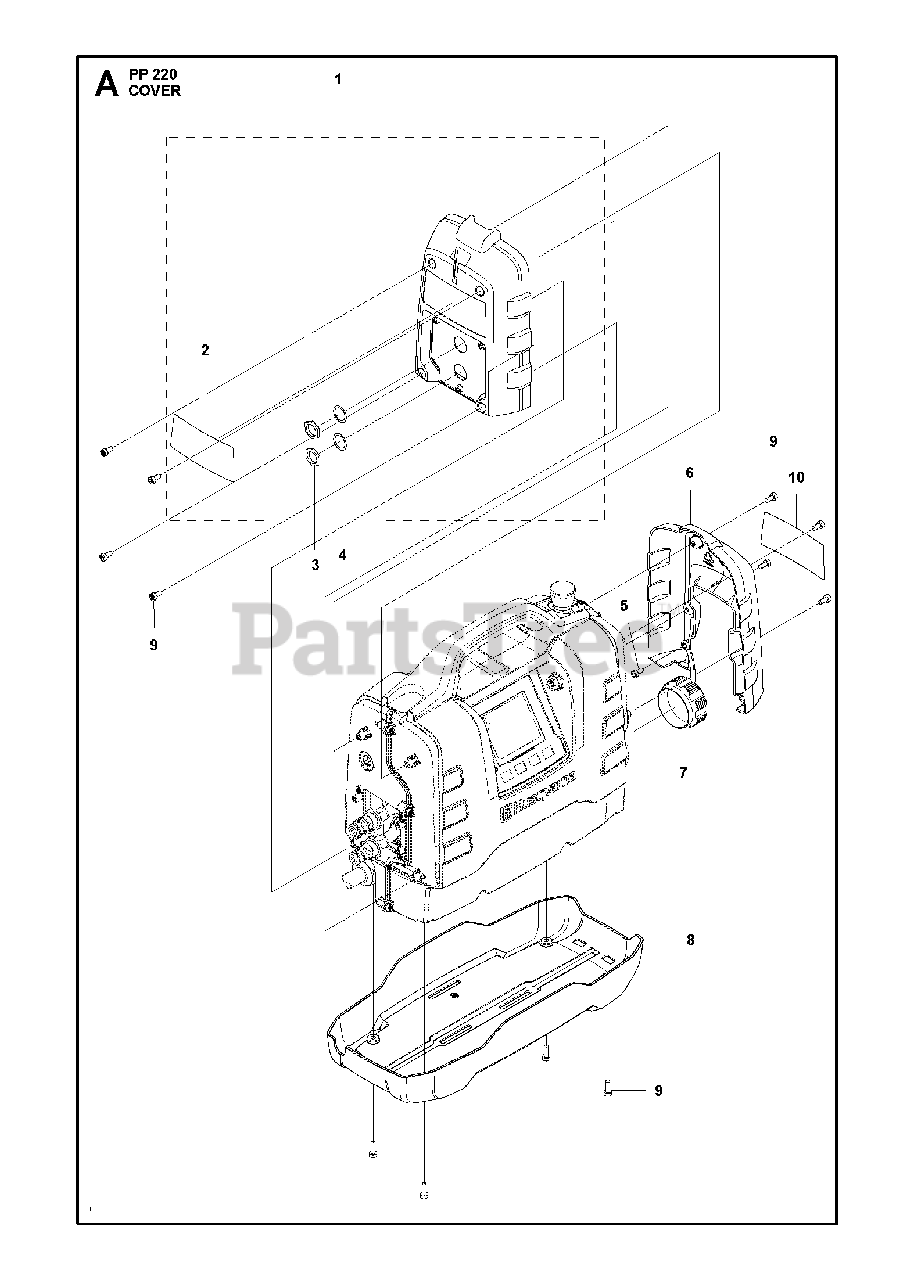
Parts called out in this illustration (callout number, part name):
1	COVEREU + AUS, Incl. 2
1	COVERUS + JP, Incl. 2
5	SCREW ITXSCT
